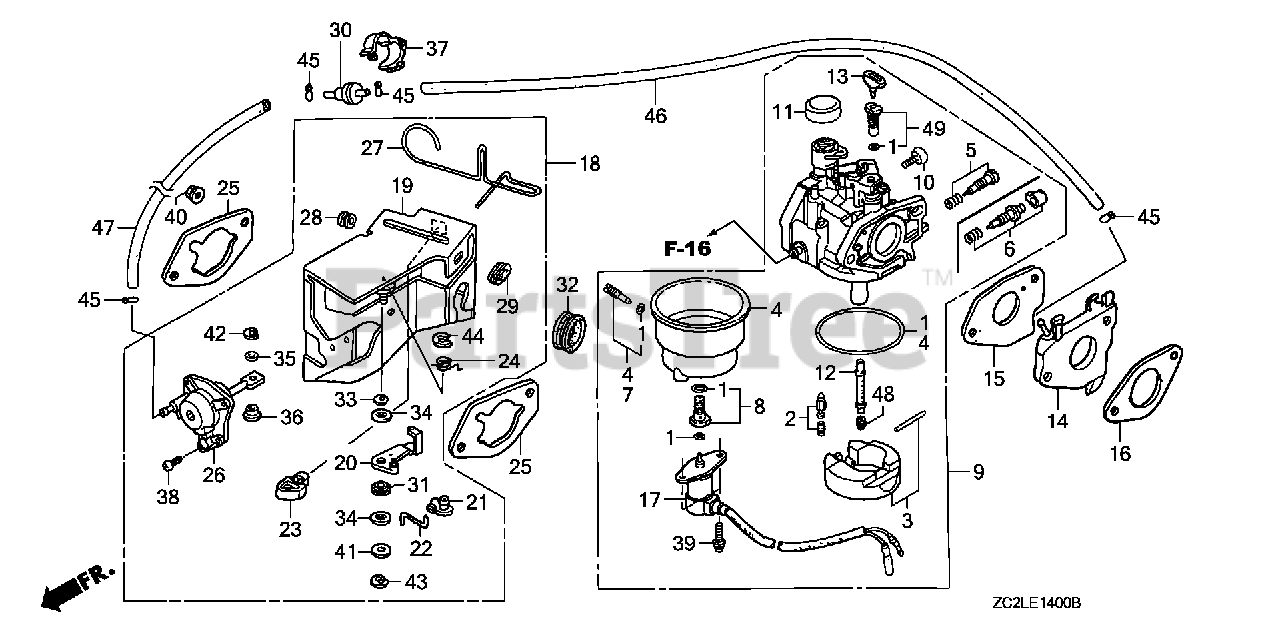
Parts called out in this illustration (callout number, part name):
1	GASKET SET
2	VALVE SET, FLOAT
4	CHAMBER SET, FLOAT
6	SCREW SET, PILOT
7	SCREW SET, DRAIN (CARBURETOR NO.)
9	CARBURETOR ASSY. (BE82B C)
10	SCREW, THROTTLE STOP
11	CAP, CHOKE DUST
12	NOZZLE, MAIN (CARBURETOR NO.)
13	COLLAR, SETTING (CARBURETOR NO.)
14	INSULATOR, CARBURETOR
15	GASKET, CARBURETOR
16	GASKET, INSULATOR
17	VALVE ASSY., SOLENOID
18	STAY ASSY., MANUAL CHOKE
19	STAY, SOLENOID
20	LEVER, CHOKE
21	JOINT, ROD
22	ROD, CHOKE
23	STOPPER, CHOKE ROD
24	SPRING, MANUAL CHOKE
25	GASKET, AIR CLEANER
26	DIAPHRAGM ASSY.
27	ROD, CHOKE CONTROL
28	GROMMET, CHOKE ROD
29	GUIDE, CHOKE ROD
31	BUSH, ARM PIVOT
32	GROMMET, FENDER
33	WASHER, CHOKE LEVER
34	SEAL, CHOKE LEVER
35	WASHER, THRUST (2.7X8)
36	COLLAR, LEVER
38	SCREW, PAN (5X12)
39	SCREW-WASHER (5X12)
40	NUT, FLANGE (6MM)
41	WASHER, PLAIN (5MM)
42	E-RING (2MM)
43	E-RING (4MM)
44	E-RING (7MM)
48	JET, MAIN (#95)
48	JET, MAIN (#98)
48	JET, MAIN (#100)
49	JET SET, PILOT (#35) (CARBURETOR NO.)
